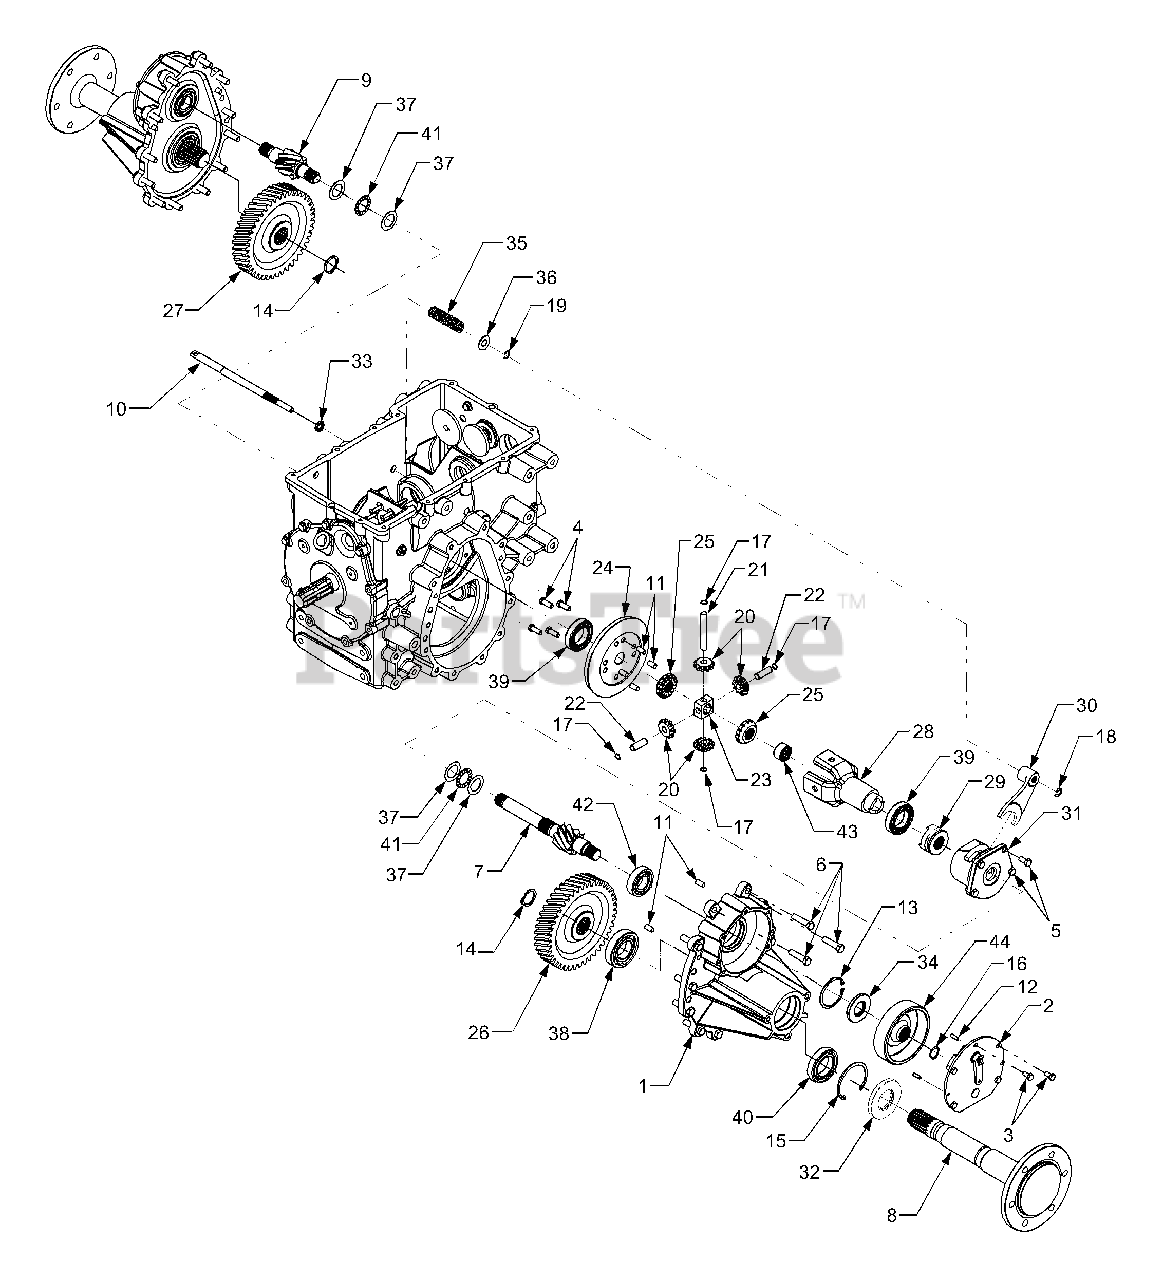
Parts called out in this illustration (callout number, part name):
1	Housing, Axle
2	Brake Assembly, Drum
3	Screw, Hex Cap Lock, 5/16-18 x .625 GR5
4	Screw, Socket Hd. Cap, 3/8-16 x 1.0
5	Screw, Hex Cap Lock, 3/8-16 x .75 GR5
6	Screw, Hex Cap Lock, 7/16-14 x 1.75 GR5
7	Shaft, Axle Stub RH
8	Shaft, Axle
9	Shaft, Axle Stub LH
10	Shaft, Differential Lock Actuator
11	Pin, Dowel, .3752 x .75
12	Pin, Dowel, .25 x .75
13	Ring, Retaining
14	Rjng, Retaining
15	Ring, Retaining
16	Ring, Retaining
17	Ring, Retaining
18	Clip, Rotor
19	Ring, Retaining
20	Gear, Differential, 10T
21	Shaft, Cross
22	Shaft, Cross
23	Block, Differential Pinion
24	Gear, Bevel, 65T
25	Gear, Miter, 14T
26	Gear, Drop Axle, 42T RH
27	Gear, Drop Axle, 42T LH
28	Carrier, Differential
29	Collar, Differential Lock
30	Yoke, Differential Lock
31	Cover, Bearing
32	Seal, Oil, 50mm x 75 mm x 10mm
33	Seal, Oil
34	Seal, Oil, 1.181 x 2.453 x .276
35	Spring, Compression
36	Washer, Flat, .56 x 1.0 x .04
37	Washer, Thrust, 1.12 x 1.75 x .03
38	Bearing, Ball
39	Bearing, Ball
40	Bearing, Ball
41	Bearing, Thrust
42	Bearing, Ball
43	Bearing, Needle
44	Drum, Brake
